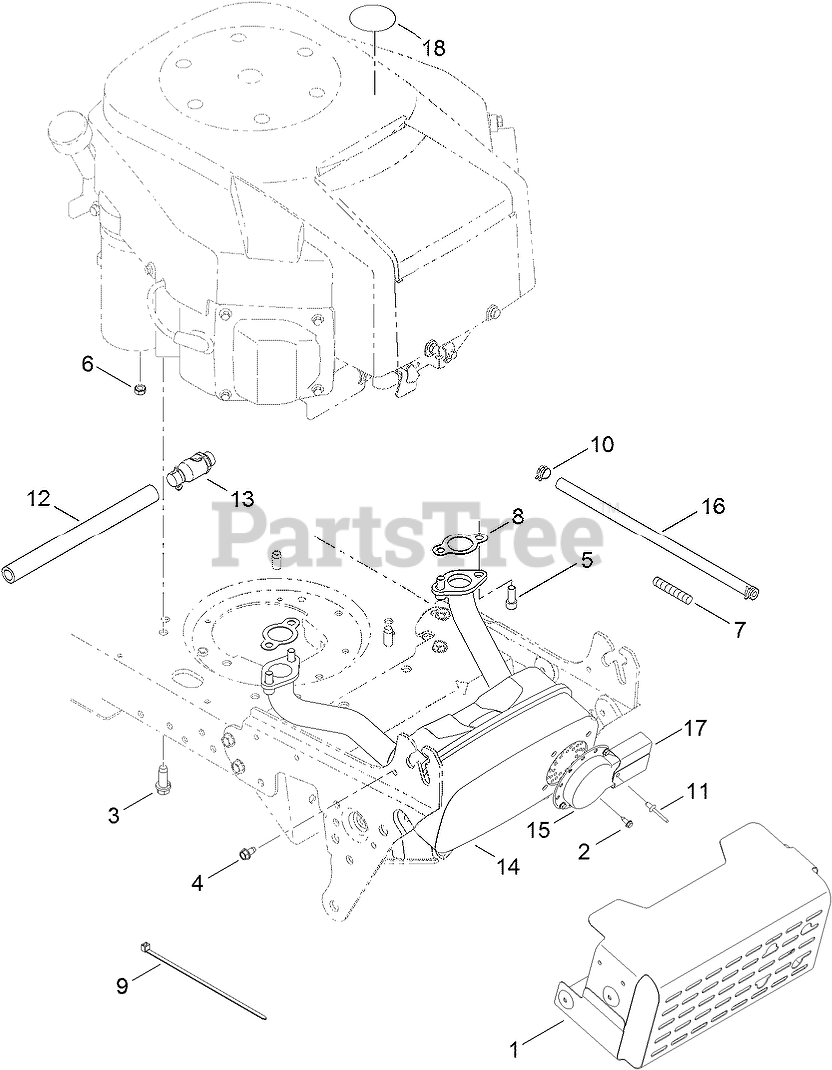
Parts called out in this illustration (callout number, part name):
1	SHIELD-MUFFLER
2	SCREW-HWHTF
3	SCREW-HH, TAP
4	SCREW-HWHTF
5	SCREW-HSH
6	NUT-SEMS
7	HOSE-VENT
8	GASKET-EXHAUST
9	TIE-CABLE
10	CLAMP-HOSE
11	RIVET-POP
12	HOSE-DRAIN
13	Drain-Oil
14	MUFFLER-TWIN
15	DEFLECTOR-MUFFLER
16	HOSE-FUEL
17	DEFLECTOR-MUFFLER
18	DECAL-CHECK OIL
